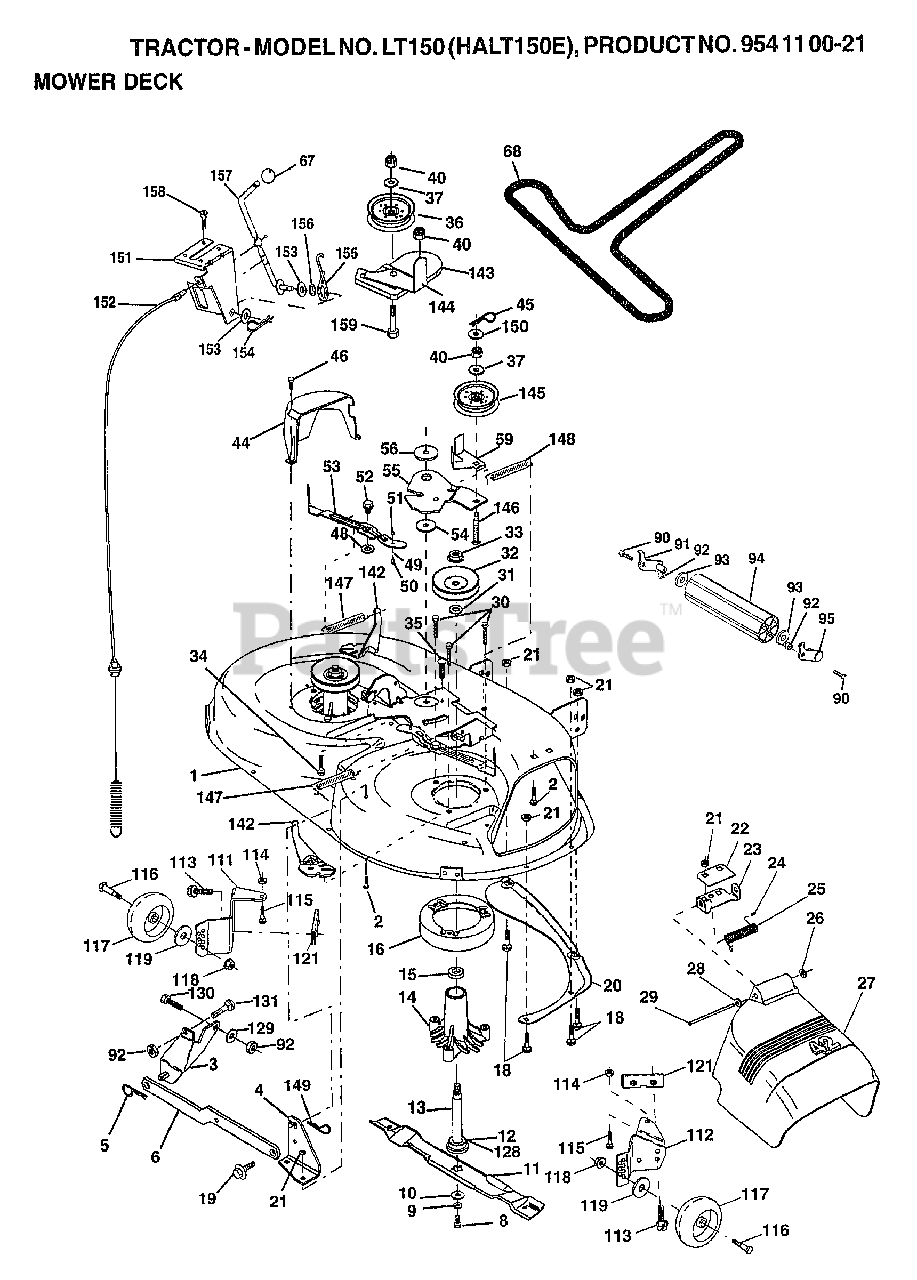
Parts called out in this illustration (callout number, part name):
1	DECK ASM
2	BOLT, CARRIAGE
9	WASHER LOCK HVY 3/8
18	BOLT RDHD SQNK 5/16-18 X 5/8
21	LOCKNUT, CROWN 5/16-18
27	SHIELD DEFLECTOR MOWER
28	WASHER 11/32 X 5/8 X 16 GA
34	BOLT
37	WASHER 13/32 X 13/16 X 16 GA
40	NUT, CROWNLOCK 3/8-16
48	WASHER HARDENED SMALLER
90	BOLT FIN HEX 3/8-16 X 1
91	BRK ASM ROLLER LH
92	LOCKNUT
93	WASHER, 17/32 X 7/8 X 16 GA.
95	BRK ASM ROLLER RH
113	SCREW
114	NUT, KEPS 5/16-18
115	BOLT
118	NUT, CENTER LOCK 3/8-16
119	WASHER 3/8 X 7/8 X 14 GA.
129	WASHER
130	BOLT FIN HEX 3/8-16 X 1
131	BOLT CARRIAGE 3/8-16X1
142	ARM SPRING BRAKE MOWER
143	BRKT ARM IDLER
144	KEEPER BELT
145	PULLEY IDLER FLAT
146	BOLT
150	WASHER, 9/32 X 3/4 X 16 GA.
151	BRACKET CLUTCH CABLE
152	42" CLUTCH CABLE
153	WASHER
154	SPRING RETAINER
155	SPRING RETENTION LEVER
158	SCREW HEX THD CUT 1/4-20X5/8 T
159	BOLT
